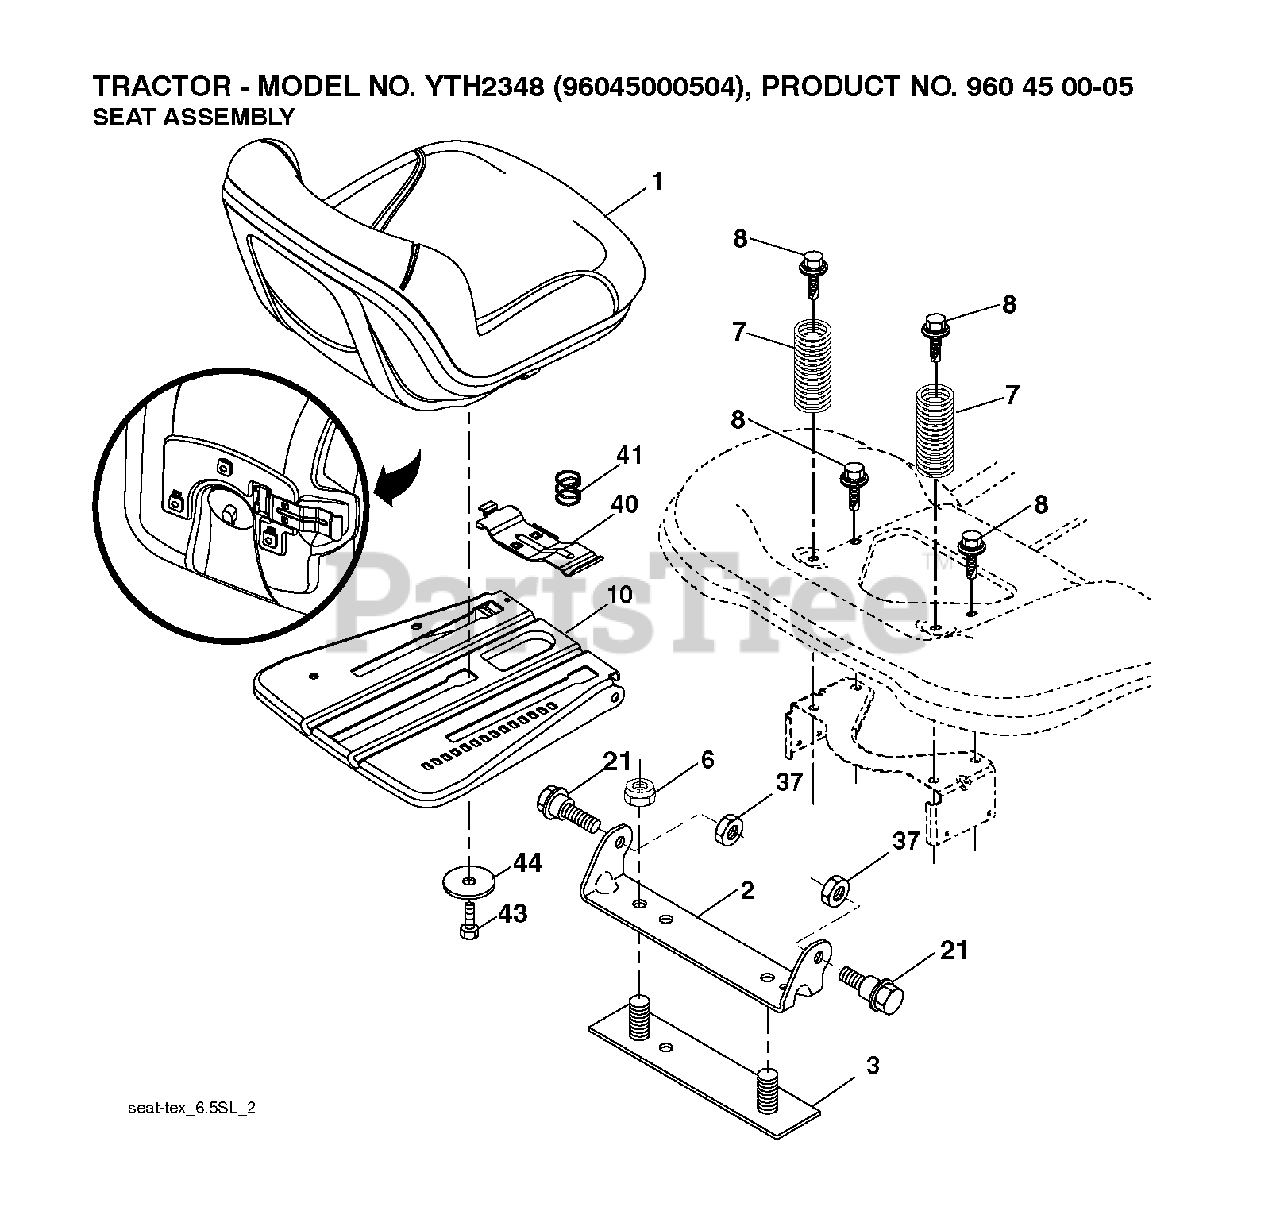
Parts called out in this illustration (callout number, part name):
1	SEAT - GREY
2	BRKT.PIVOT.FENDER
3	STRAP
6	NUT
7	SPRING COMPRESSION
8	BOLT, 5/16-18 X 1 3/4
10	PAN.ASM.SEAT.3PT
21	BOLT.SHOULDER.5/16-18
37	NUT.71038.31-18.HEX.NYLOCK
40	HANDLE.SLIDE.SEAT.TEX.BLACK
41	SPRING.LATCH.SEAT.TEX
44	WASHER 13/32 X 2-3/8 X 12GA
